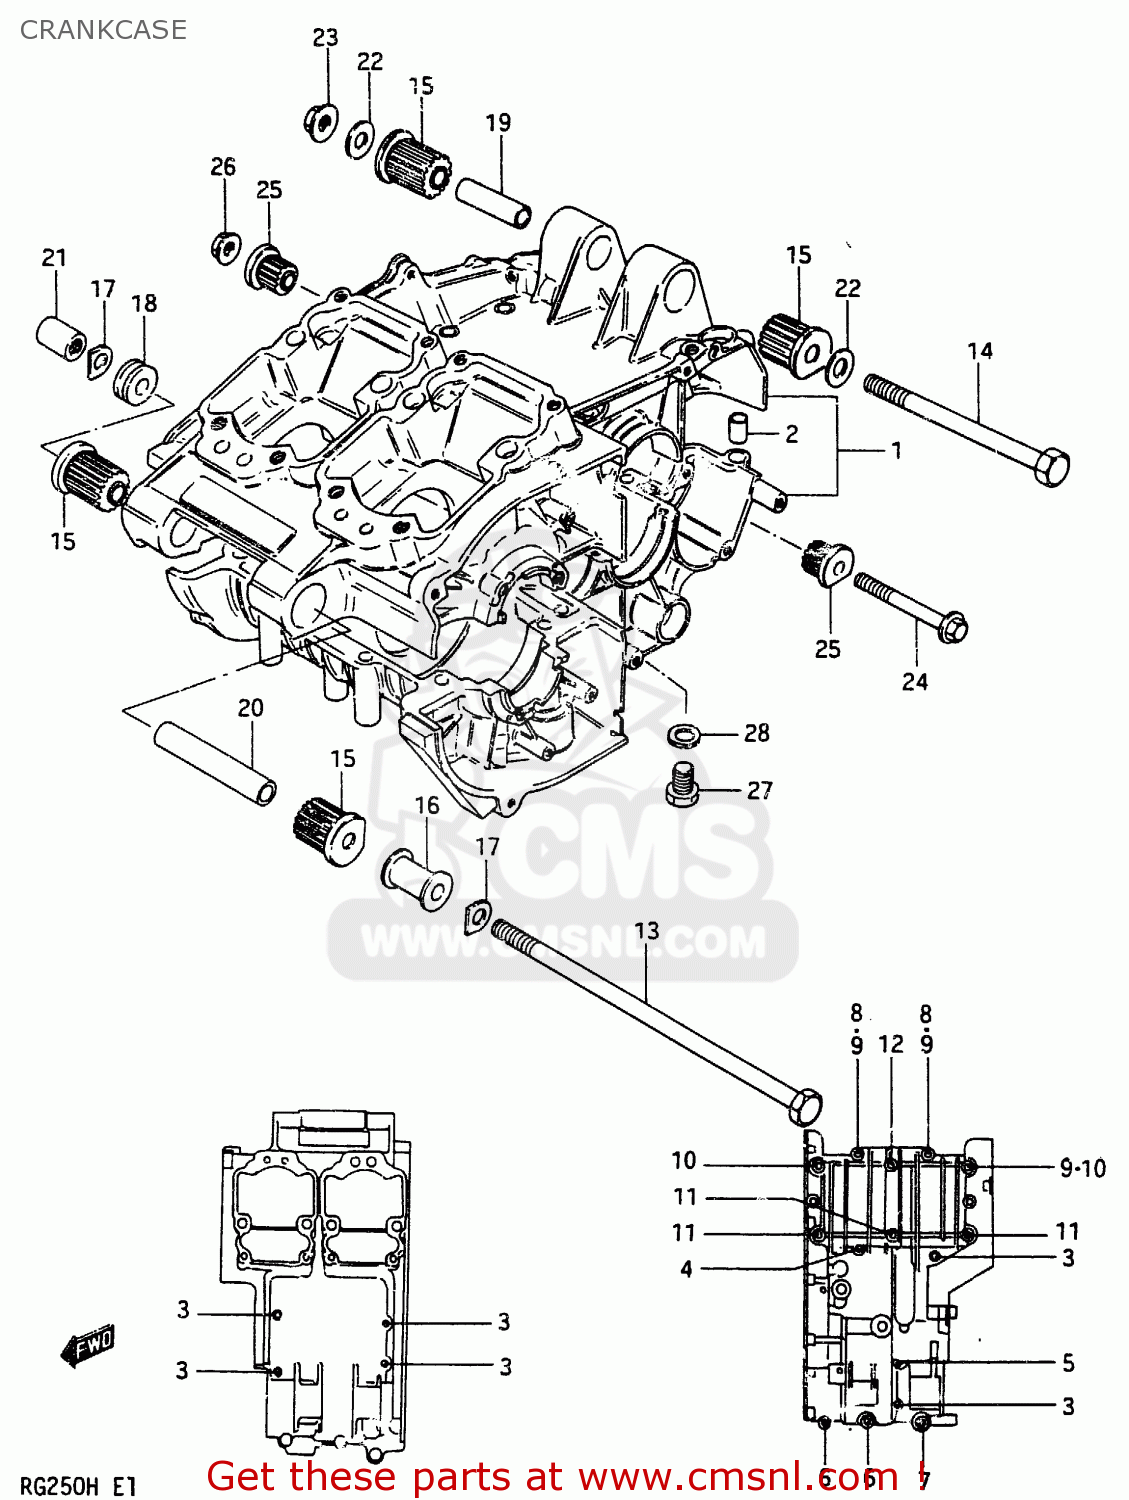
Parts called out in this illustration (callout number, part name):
1	CRANKCASE SET
2	PIN
3	BOLT ,6X60
4	BOLT
5	BOLT (6X90)
6	BOLT 8X40
7	BOLT
8	BOLT 8X60
9	GASKET 8.2X14X1 (NAS)
10	BOLT (8X70)
11	BOLT
12	BOLT 8X85
13	BOLT (10X225)
14	BOLT (10X140)
15	BUSH
16	SPACER,ENGINE MOUNT
17	PLATE, ENGINE MOUNT
18	SPACER, ENGINE MOUNT (L:11)
19	SPACER(10.2X16X40)
20	SPACER
21	NUT
22	WASHER (10.5X24X2.3)
23	NUT 10MM
24	BOLT (8X65)
25	BUSHING
26	NUT
27	PLUG
28	GASKET(14X19.2X2) (NAS)
